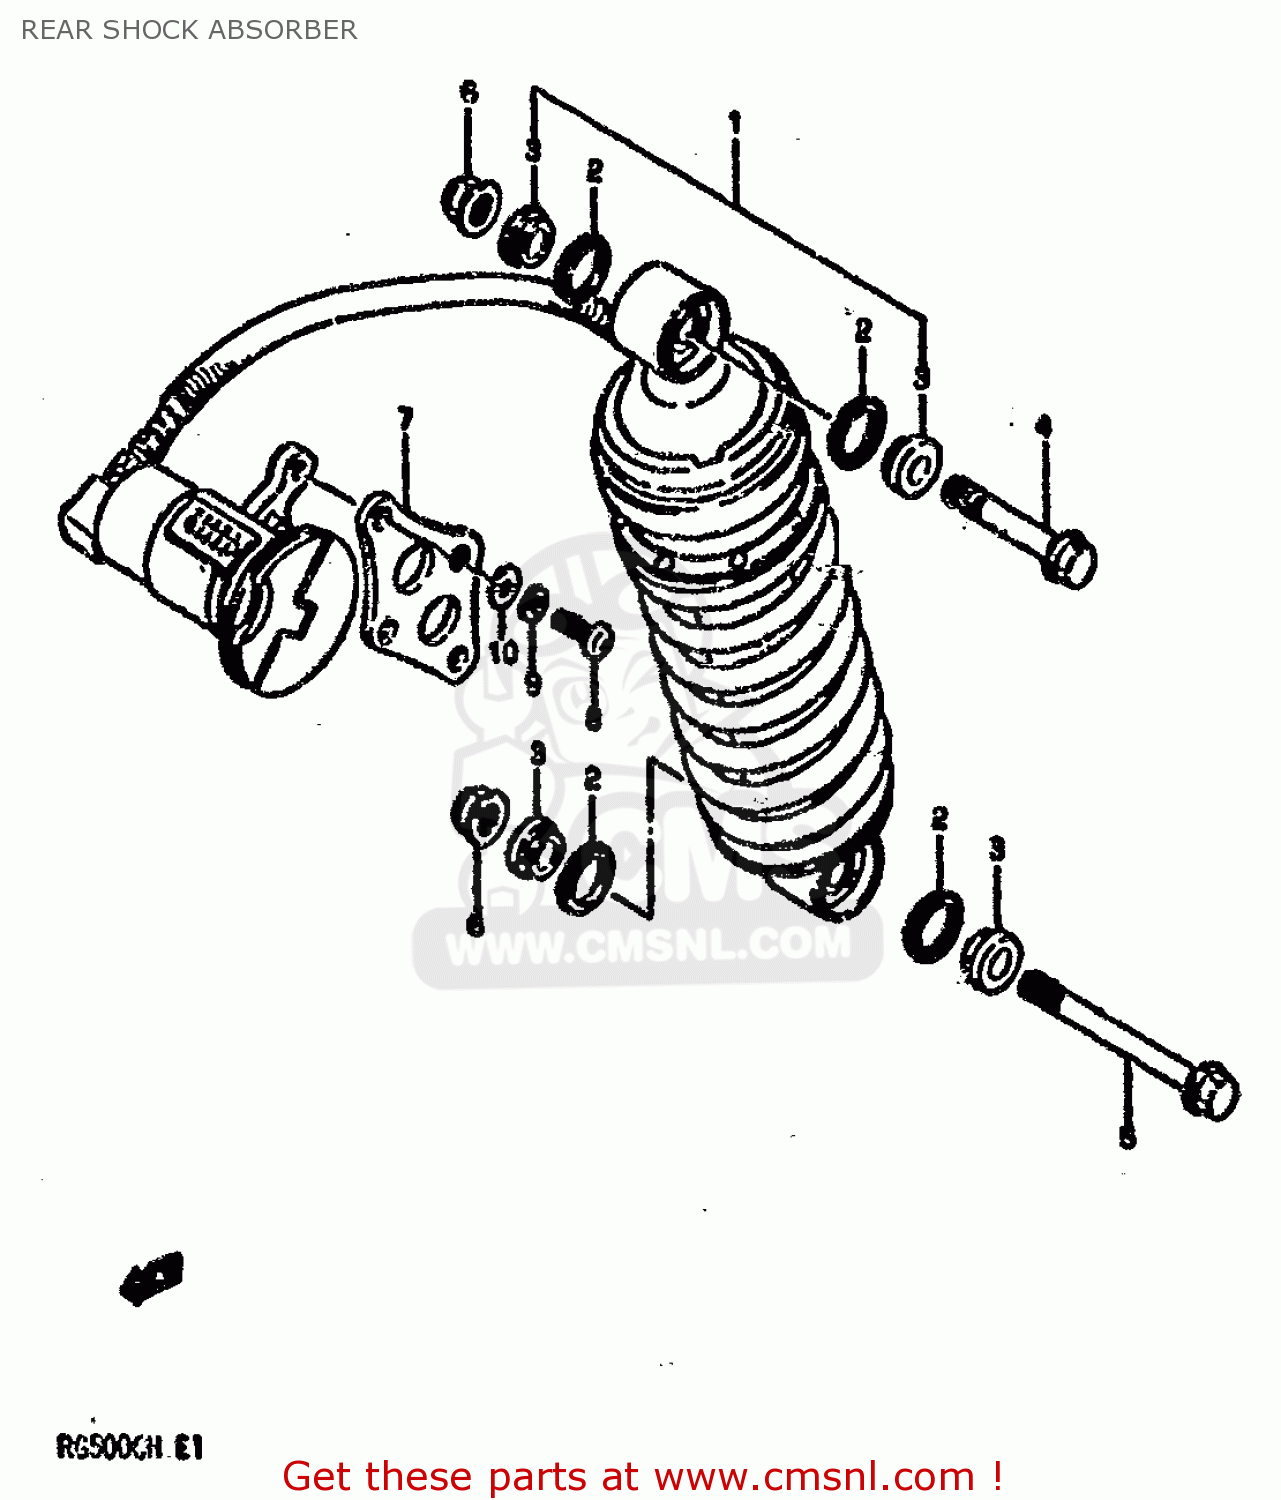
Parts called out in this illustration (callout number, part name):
1	ABSORBER ASSY,REAR SHOCK
2	SEAL,DUST RR SHOCK ABSORBER
3	COLLAR
4	BOLT(10X54)
5	BOLT 10X90
6	NUT
7	BRACKET,SPRING ADJUSTER
8	SCREW
9	WASHER,LOCK
10	WASHER
